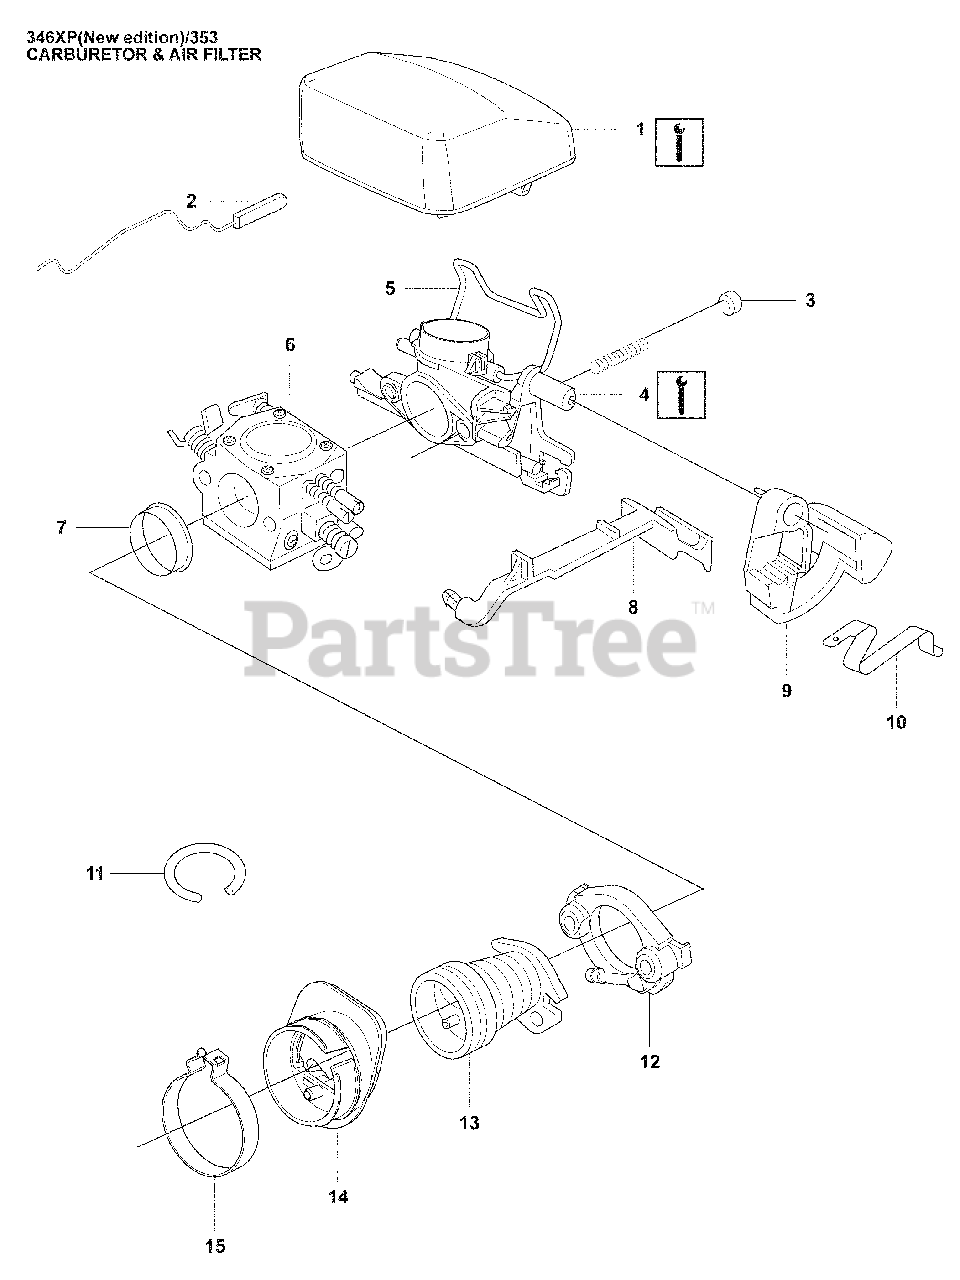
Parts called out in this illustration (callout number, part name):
1	Air Filter, Nylon B
1	Air Filter, Nylon Y
1	Air Filter, Felt
2	Throttle Rod
4	Elbow Inlet
5	Filter Clamp
6	Carburetor
7	Ring
8	Choke Control Lever
11	Impulse Hose
15	Intake Clamp
